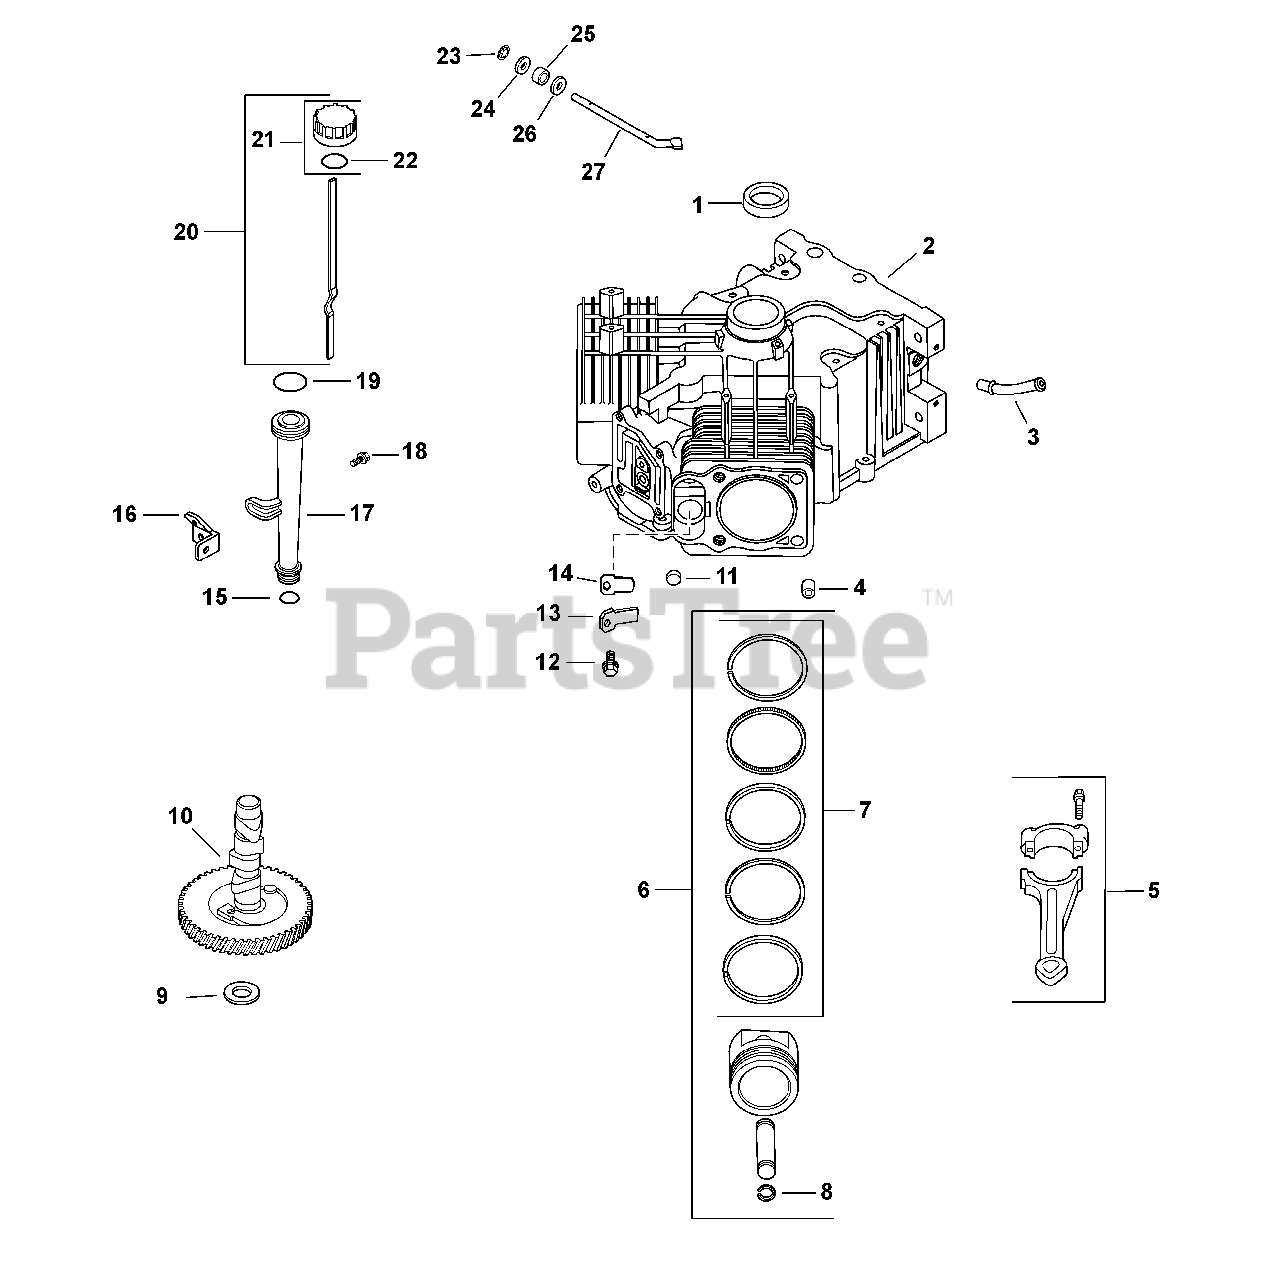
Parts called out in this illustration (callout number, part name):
2	Crankcase
5	Connecting Rod (STD)
5	Connecting Rod (.25)
6	Piston Kit w/ Ring (STD) (Inc. 7 & 8)
6	Piston Kit w/ Ring (.08)
6	Piston Kit w/ Ring (.25)
6	Piston Kit w/ Ring (.50)
7	Piston Ring Set (STD)
7	Piston Ring Set (.08)
7	Piston Ring Set (.25)
7	Piston Ring Set (.50)
8	Piston Pin Retainer
9	Camshaft Shim (White .028")
10	Camshaft Kit (Inc. KH-25-357-14-S)
12	Flange Screw, M5 x 0.8 x 10
13	Breather Reed Retainer
14	Breather Reed
15	Lower Oil Fill Tube O-Ring
16	Oil Fill Tube Bracket
17	Oil Fill Assembly Tube
18	Flange Screw, M5 x 0.8 x 16
19	Upper Oil Fill Tube O-Ring
20	Dipstick, Assembly (Inc. 21 & 22)
21	Oil Fill Cap Kit (Yellow) (Inc. 22)
22	Dipstick O-Ring
23	Ring Retainer
24	Flat Washer, 9 mm
25	Governor Cross Shaft Seal
26	Flat Washer, 1/4"
27	Governor Cross Shaft
